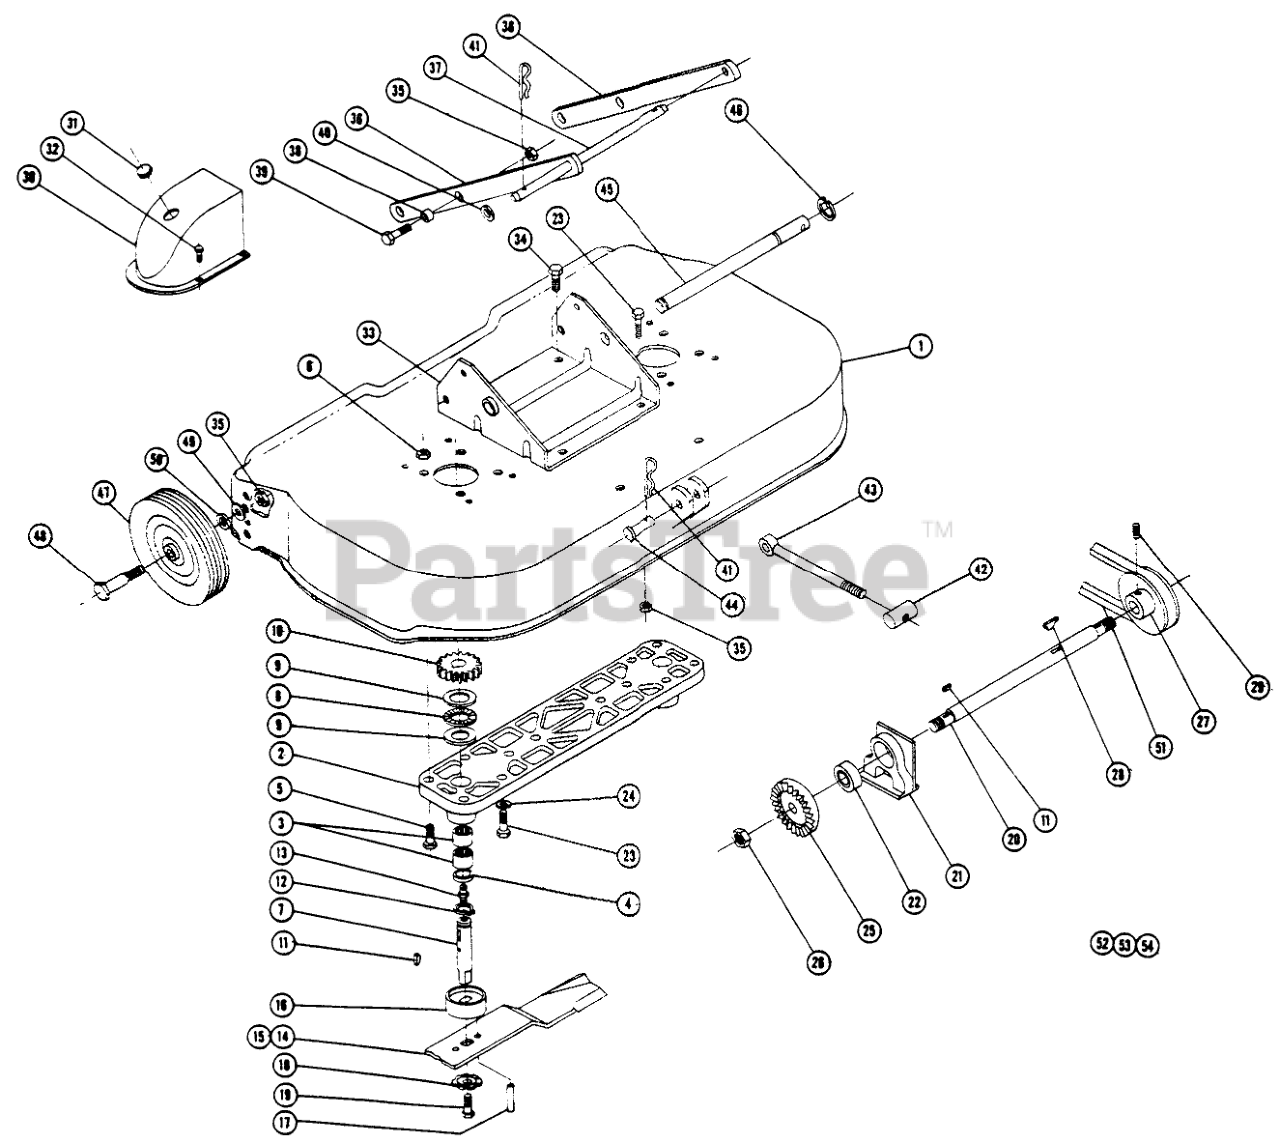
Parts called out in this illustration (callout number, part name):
1	Ass-y. Deck
5	Bolt 5/16-18 x
6	Nut-Nylok
9	WASHER-THRUST
17	SPIROL ROLL PIN
19	Bolt 3/8-16 x 7/8
21	BEARING SUPPORT
23	Bolt 3/8-16 x 1
24	Lockwasher
27	Pulley
29	Set Screw 5/16-18 x 5/16
31	PLUG BUTTON
32	SCREW
33	Hanger
34	Bolt 3/8-16 x 3/4
35	3/8-16 E.S.
36	Link-Rear Parallel
39	Bolt 3/8-16 x 7/8
40	Washer
41	Hairpin
44	Pin-Clevis
45	Shaft-Belt Tightener
46	E-RING
48	BOLT-SHOULDER
49	Washer 3/8
50	Spacer
51	V BELT
52	Decal-Belt Diagram
53	Decal
